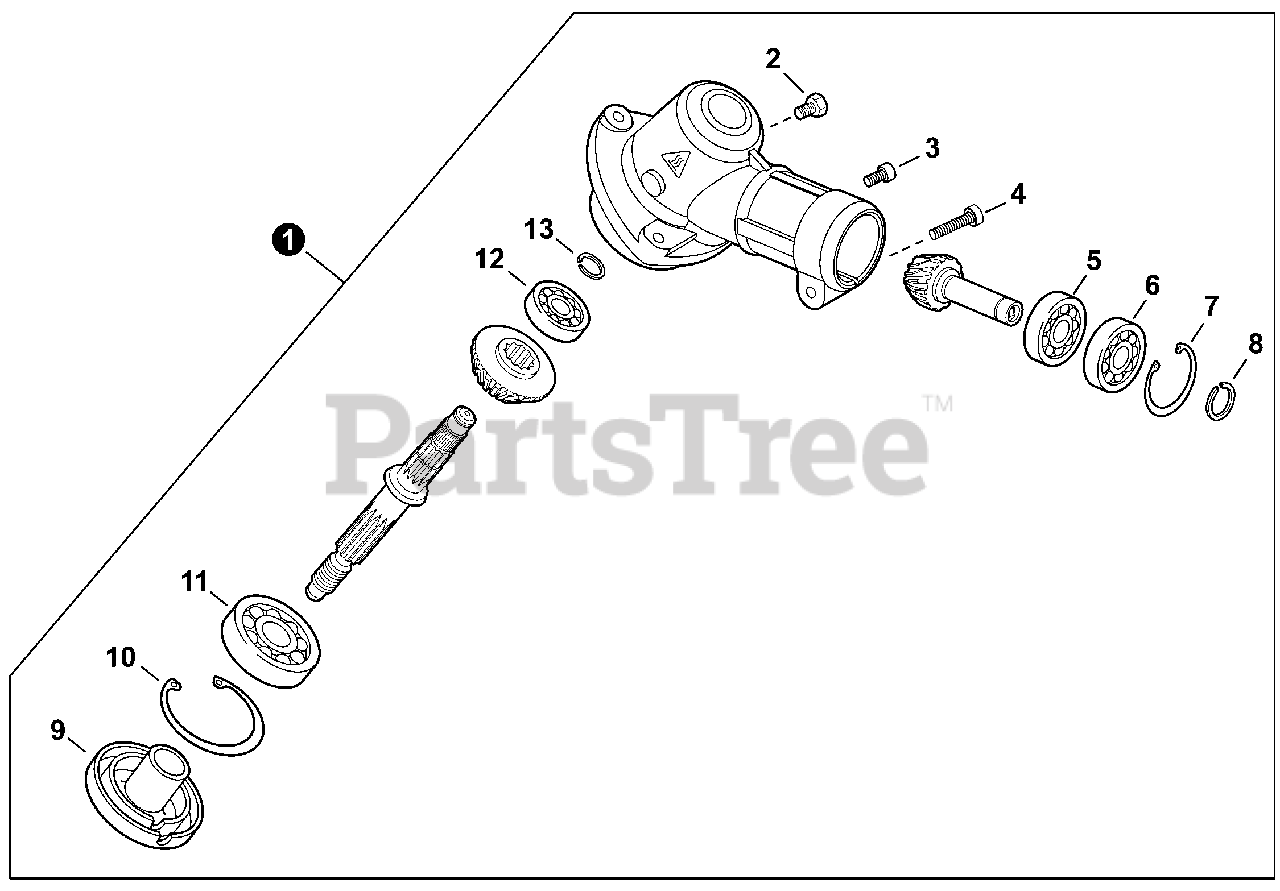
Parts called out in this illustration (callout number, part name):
1	GEAR CASE ASSY
2	BOLT M8×8
3	BOLT, TORX 5×12
4	BOLT, TORX 6×25
5	BEARING, BALL 6900
6	BEARING, BALL 6900-Z
7	RING, SNAP Ø22
8	RING, SNAP Ø10
9	PLATE, ADAPTOR - UPPER
10	RING, SNAP Ø42
11	BEARING, BALL 6302
12	BEARING, BALL 629
13	RING, SNAP Ø12
